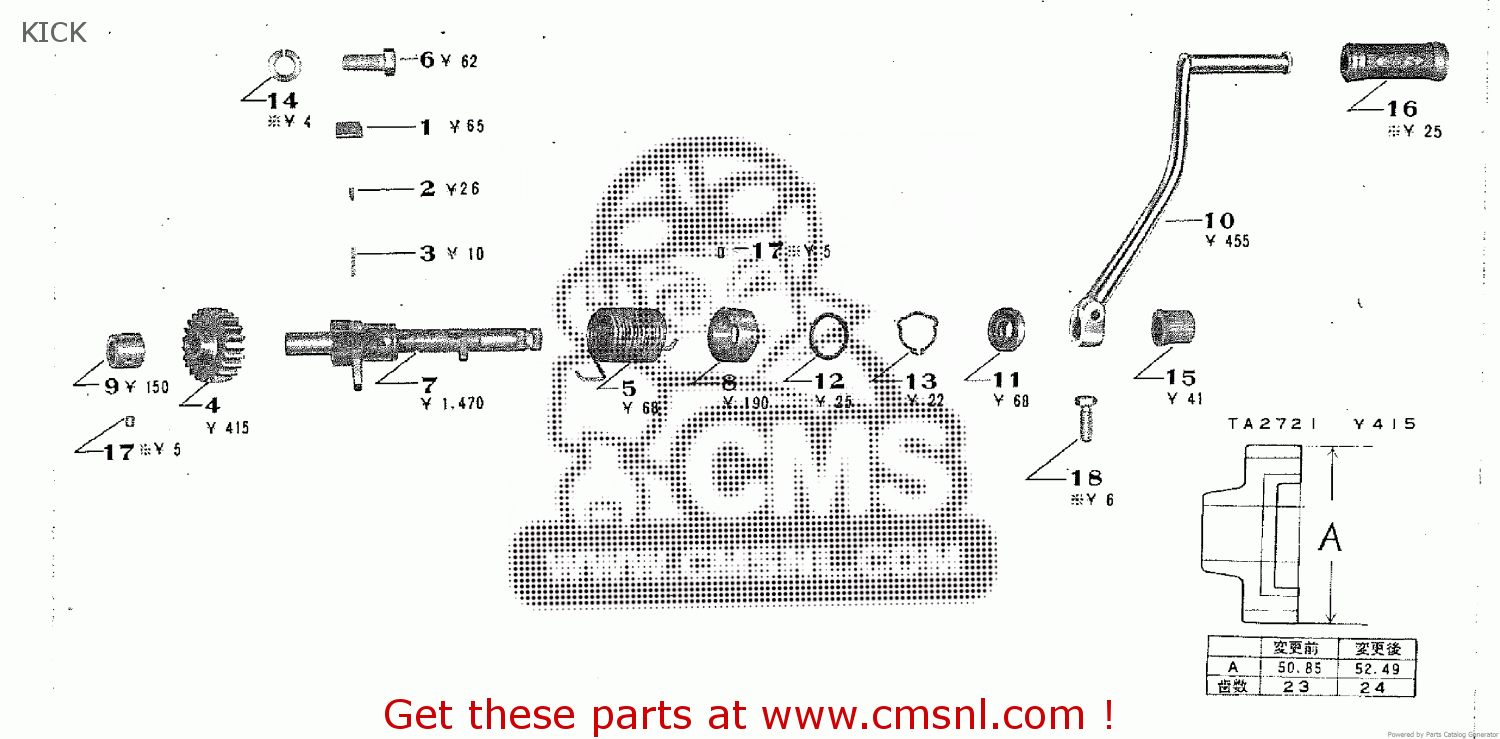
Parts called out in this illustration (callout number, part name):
1	KICK PAWL
2	KICK PAWL ROLLER
3	KICK PAWL SPRING
4	KICK PAWL PINION
5	KICK SHAFT RETURN SPRING
6	KICK STOPPER
7	KICK SHAFT
8	RIGHT KICK SHAFT BUSH
9	LEFT KICK SHAFT BUSH
10	KICK LEVER
11	KICK SHAFT OIL SEAL
12	KICK SHAFT THRUST WASHER
13	KICK SHAFT SET CIRCLIP
14	KICK STOPPER SET SPRING WASHER
15	KICK SHAFT CAP
16	KICK PEDAL RUBBER
17	6X10 ROLLER
18	8X25 HEXAGON BOLT
